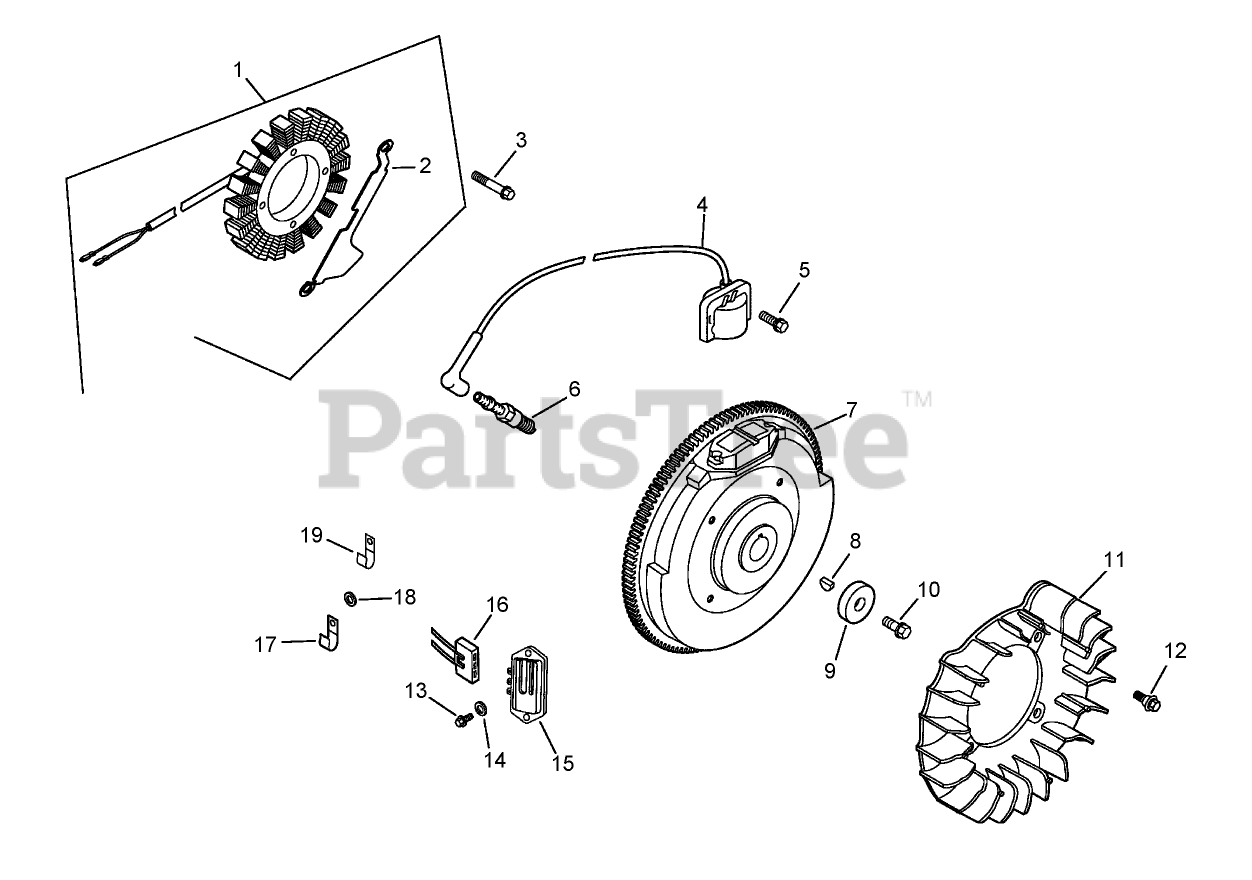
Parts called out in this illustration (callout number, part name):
1	Stator Kit (Includes 2)
2	Bracket-Wire, Stator
3	SCREW-THREAD FORMING (M5X0.8X25)
4	Module-Ignition
5	SCREW-FLANGE, THREAD FORMING (M5X.8X20)
6	SPARK PLUG (PRO SERIES)
7	Flywheel
8	KEY (3/16 X 5/8)
9	WASHER-FLAT (13/32)
10	SCREW-FLANGE (M10X1.5X45)
11	Fan
12	BOLT-SHOULDER (M6x1.0x16)
13	SCREW-PHL HD (11-16X.88)
14	WASHER-FLAT (.188)
15	Rectifier-Regulator
16	Connector (3 contact)
17	CLIP-CABLE
18	WASHER-FLAT (1/4)
19	Clip-Cable (for B+ lead)
